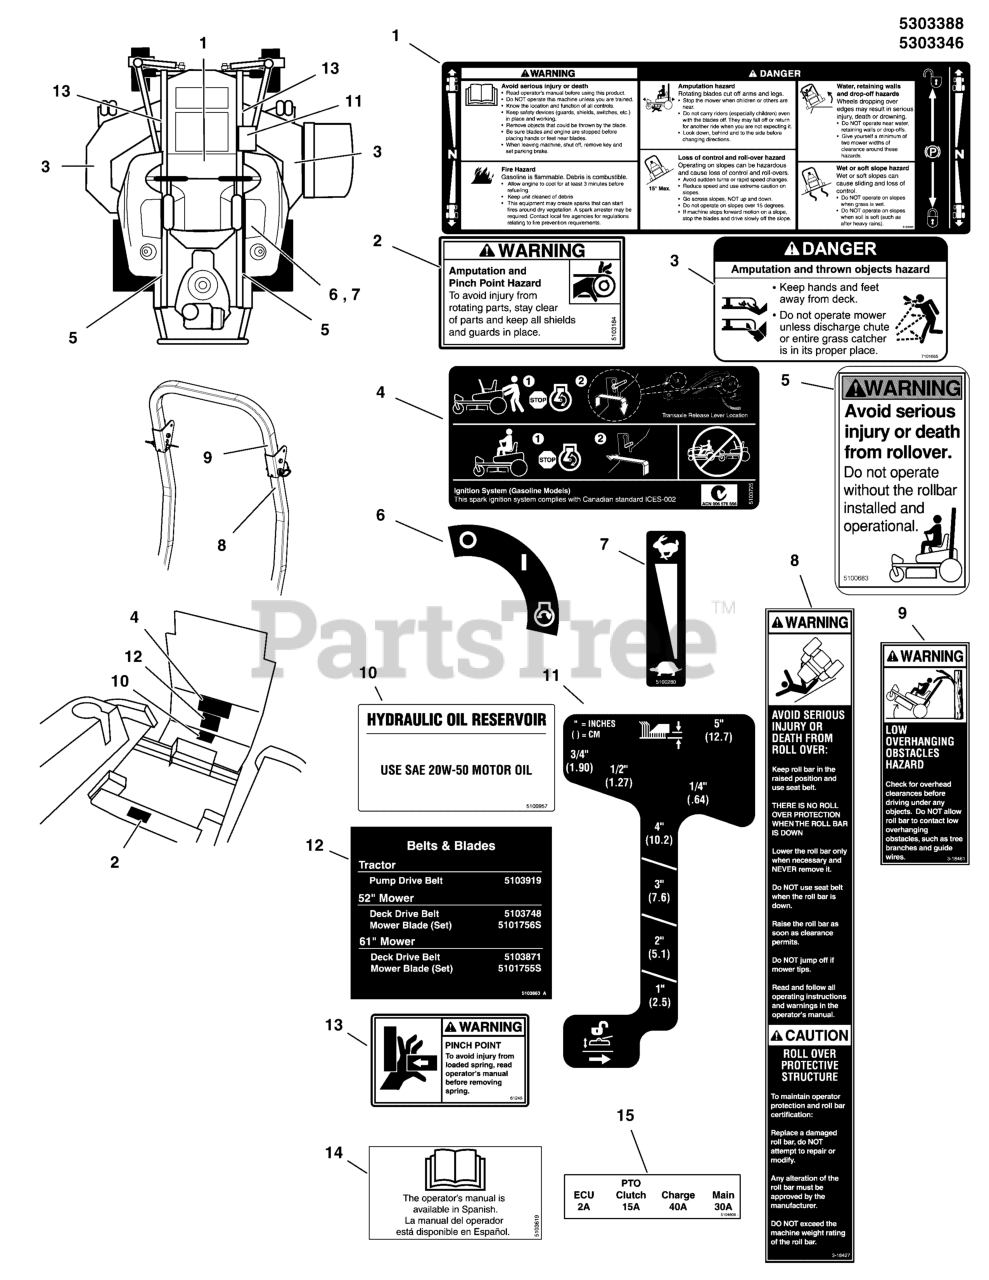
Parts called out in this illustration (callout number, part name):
1	DECAL, MAIN SAFETY
2	DECAL, WARNING, HAND IN BELT, ENG ONLY
3	DECAL, DANGER DO NOT OPERATE W/O DEFLECT
4	DECAL, TRANSAXLE RELEASE, S125XT
5	DECAL, WARNING, ROLL BAR
6	DECAL, IGNITION SWITCH
7	DECAL, THROTTLE CONTROL
9	DECAL, WARNING OVERHANG, ROPS
10	DECAL, HYDRAULIC OIL, SAE 20W50
11	DECAL, CUT HEIGHT, S125XT
12	DECAL, BELT & BLADE, S125XT
13	DECAL, PINCH POINT
14	DECAL, MANUAL AVAIL IN SPANISH
15	DECAL, FUSE LOCATION, KAWI EFI
